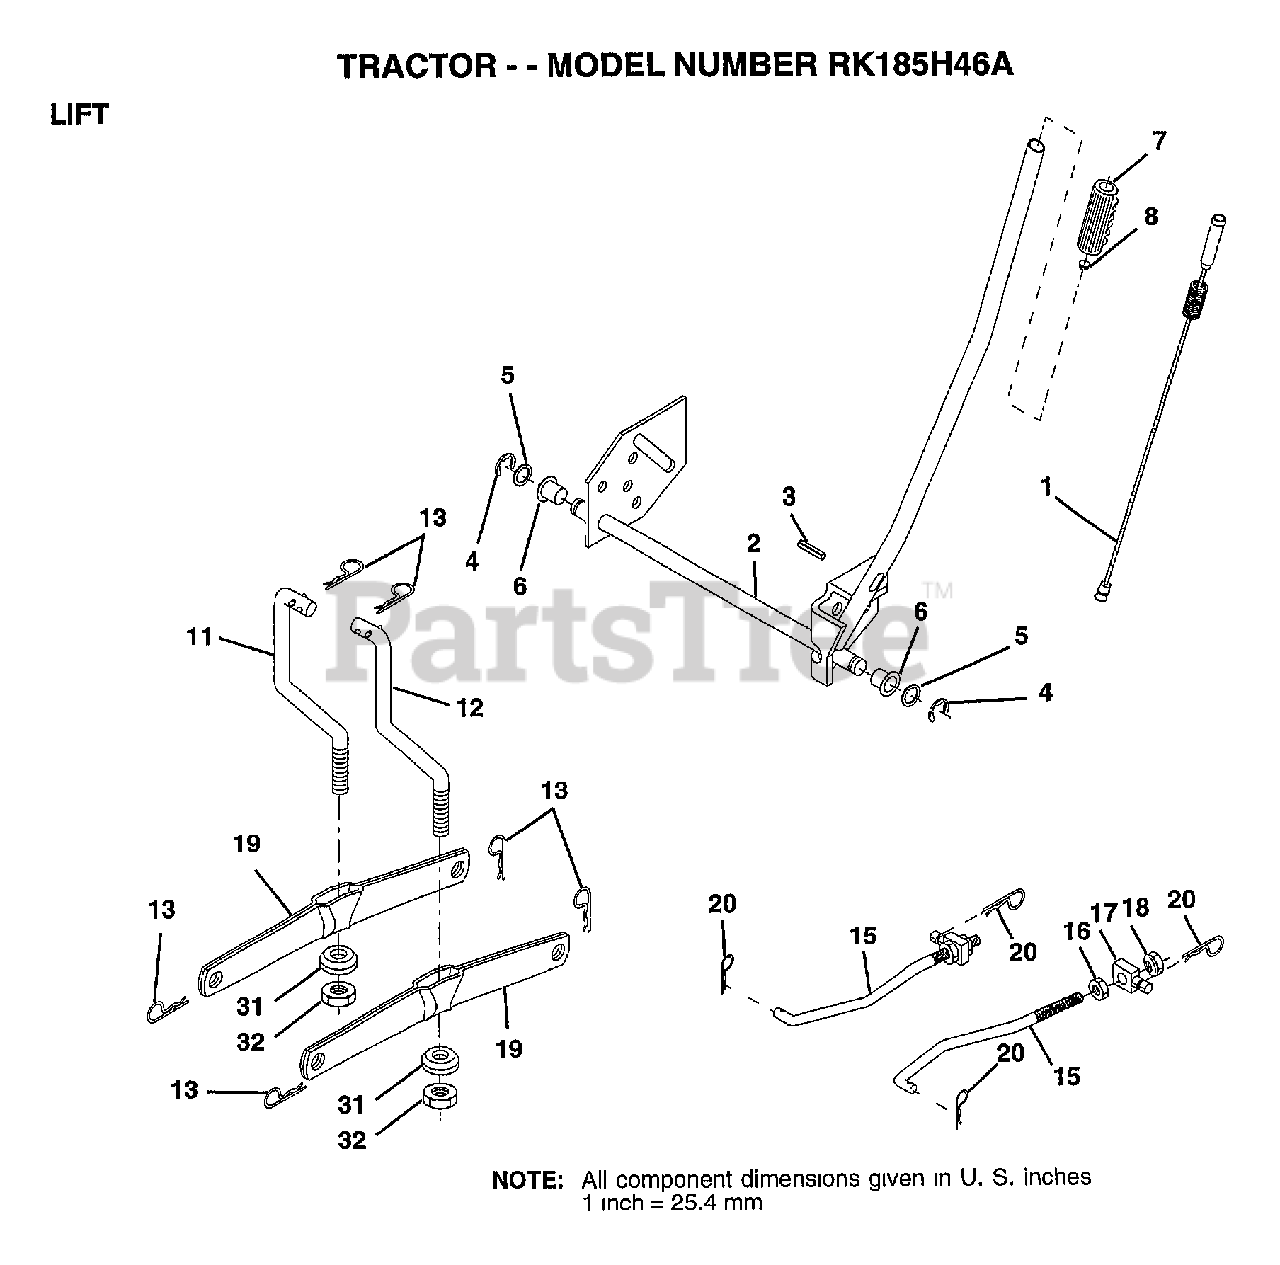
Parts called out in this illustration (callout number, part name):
1	WIRE ASM W.SPRING
2	"SHAFT ASM LIFT,RH"
3	PIN-GROOVE LT
5	WASHER
6	NYLON BEARING
7	GRIP HANDLE
15	LINK.FRONT
16	NUT
17	TRUNION
18	NUT LTV
19	ARM SUSP REAR
20	RETAINER SPRING
31	BEARING PVT LH
32	NUT.CROWNLOCK.3/8
